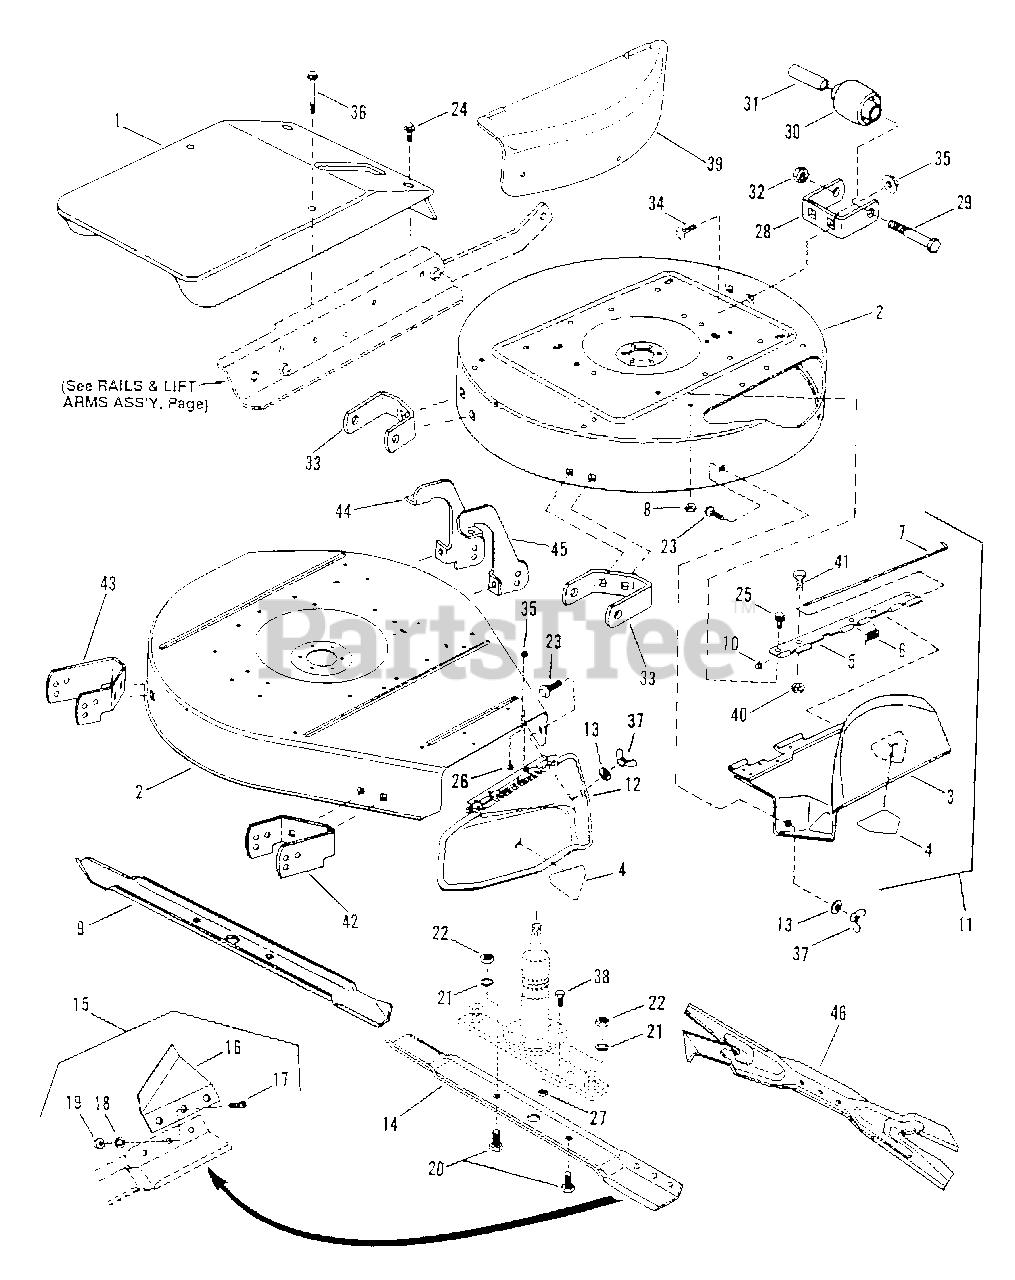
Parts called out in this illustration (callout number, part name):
1	COVER, Spindle
2	25" DECK (Includes decals)
2	28" DECK (Includes decals)
2	30" DECK (Includes decals & deflector)
2	33" DECK (Includes decals)
3	DEFLECTOR, Discharge (25" Deck)
3	DEFLECTOR, Discharge (28" & 33" Deck)
4	DECAL, Danger (Cut Finger)
5	HINGE, Deflector
6	SPRING, Hinge
7	PIN, Hinge
8	NUT, 5/16-18 Hex Flange Lock
9	BLADE, 25" Mulcher
9	BLADE, 28" Mulcher
9	BLADE, 33" Mulcher
10	NUT, Push
11	ASSEMBLY, Discharge (25" Deck)
11	ASSEMBLY, Discharge (28" & 33" Deck)
12	ASSEMBLY, Discharge (30" Decks)
13	WASHER, 5/16 Flat
14	25" BLADE
14	28" BLADE
14	30" BLADE
14	33" BLADE
15	AIR LIFT KIT, Hi-Vac
16	AIR LIFT, Hi-Vac (3 hole)
17	SCREW, 5/16-24 x 11/16" Machine
18	WASHER, 5/16-24 Internal Tooth Lock
19	NUT, 5/16-24 Hex
20	SCREW, 1/2-20 x 1" Hex Head Cap
21	WASHER, 1/2 Internal Tooth Lock
22	NUT, 1/2-20 Hex Jam
23	BOLT, 5/16-18 x 3/4" Short Neck Carriage
24	SCREW, 1/4-20 x 5/8" Self-Tapping
25	SCREW, 5/16-18 x 1/2" Self-Tapping
26	BOLT, 5/16-18 x 1/2" Hex Flange Lock
27	NUT, 3/18-16 Hex Flange Lock
28	BRACKET, Gage Wheel (Front)
29	SCREW, 38-24 X 3-3/4" Hex Head Cap
30	WHEEL, Gage
31	SPACER
32	NUT, 3/8-24 Hex Lock
33	BRACKET, Gage Wheel (Rear)
34	BOLT, 5/16-18 x 1/2" Short Nk Carr
35	NUT, 5/16-18 Hex Flange Lock
36	SCREW, 1/4-20 x 3-1/2" Self-Tapping
37	NUT, 5/16-18 Wing
38	BOLT, 3/8-16 3/4" Hex Flange Lock
39	COVER, 25" Mulcher
39	COVER, 28" Mulcher
39	COVER, 33" Mulcher
40	NUT, 5/16-18 Hex Flange Lock Grade 5
41	BOLT, Fogg Lock 1/4-20 x 1/2
42	BRACKET, Anti Scalp, 30" Rea Right Hand
43	BRACKET, Anti Scalp, 30" Rear Left Hand
44	BRACKET, Anti Scalp, 30" Front Left Hand
45	BRACKET, Anti Scalp, 30" Front Right Hand
46	BLADE, Ninja 28"
46	BLADE, Ninja 30"
46	BLADE, Ninja 33"
46	BLADE, Mulching 25"
